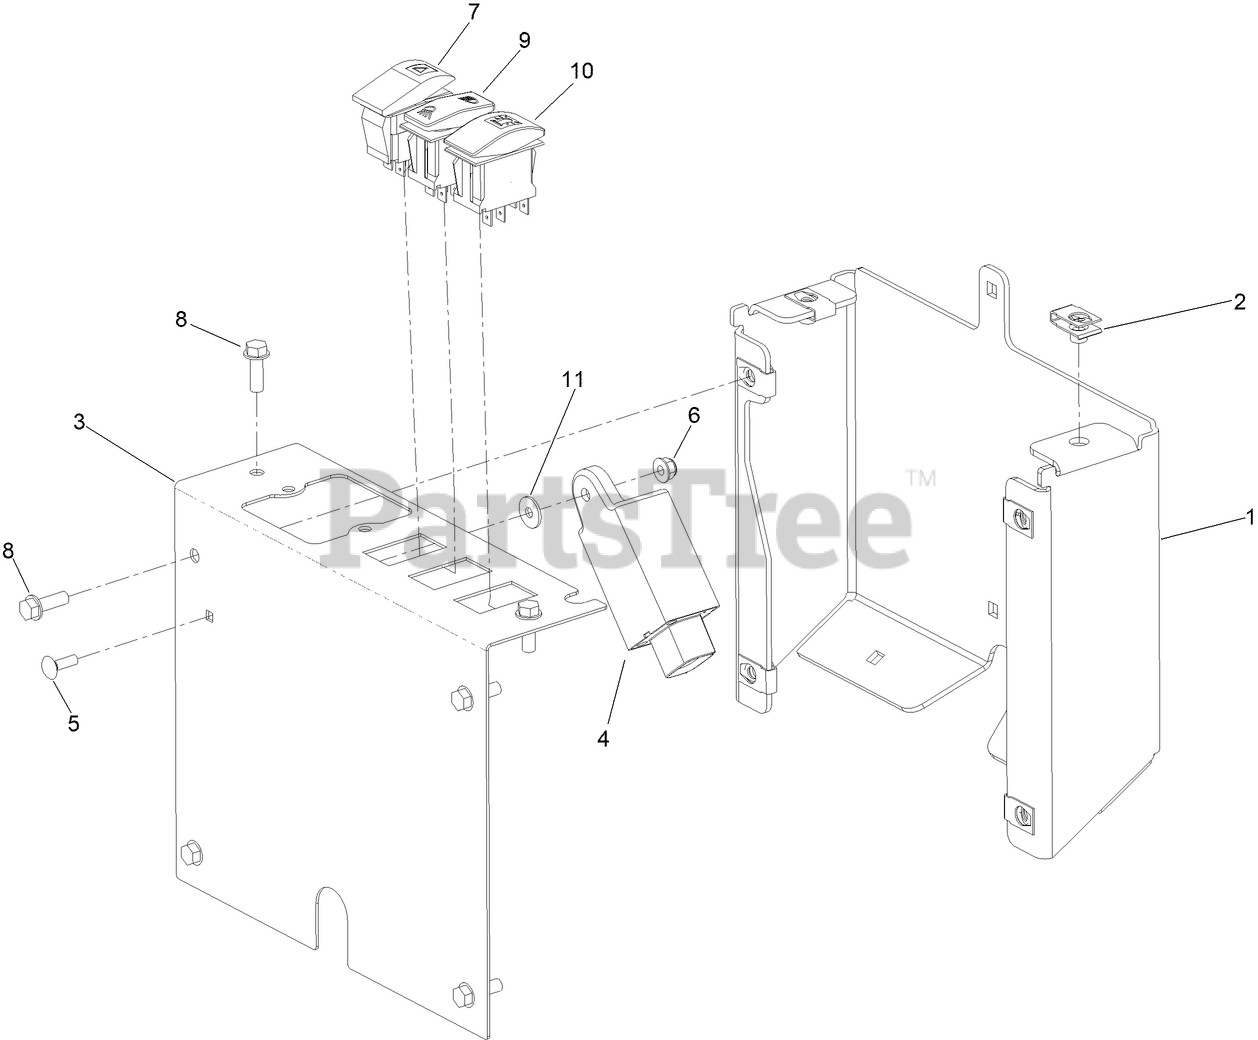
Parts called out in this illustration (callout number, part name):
1	PANEL, CONTROL
3	CONTROL-COVER
4	FLASHER-DUAL RATE
5	BOLT-CARR
6	NUT-HF
7	SWITCH-ROCKER, ON/NONE/ON
8	SCREW-HWH
9	SWITCH-ROCKER
10	SWITCH-BEACON
11	WASHER-PLAIN
